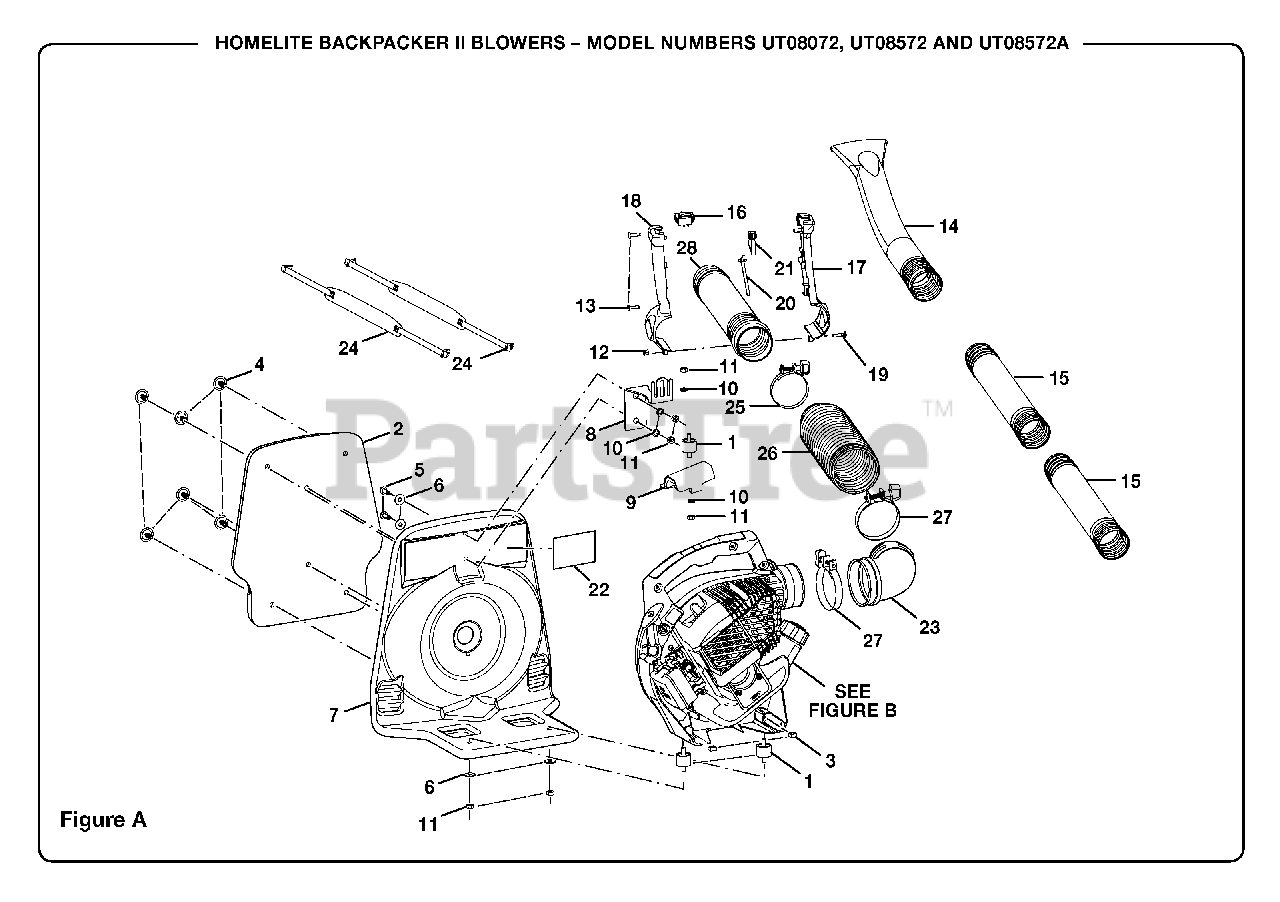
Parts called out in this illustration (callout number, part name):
1	VIBRATION ISOLATOR
2	FOAM PAD
3	SQUARE NUT
4	PUSH CLIP
5	SCREW (1/4-20 x 3/4 in.)
6	FLAT WASHER
7	BLOWER FRAME
8	FRAME BRACKET
9	ISOLATOR BRACKET
10	LOCK WASHER
11	HEX NUT
12	WING NUT
13	SCREW (10-14 x 3/4 in. TORX TRUSS HD.)
14	SWEEPER NOZZLE
15	STRAIGHT TUBE
16	SWITCH
17	HANDLE CONTROL - RT
18	HANDLE CONTROL - LT
19	BOLT
20	TRIGGER LATCH
22	BACKPACKER LABEL
24	CARRYING STRAP
25	CLAMP
26	BELLOWS
27	TUBE CLAMP
28	UPPER TUBE
